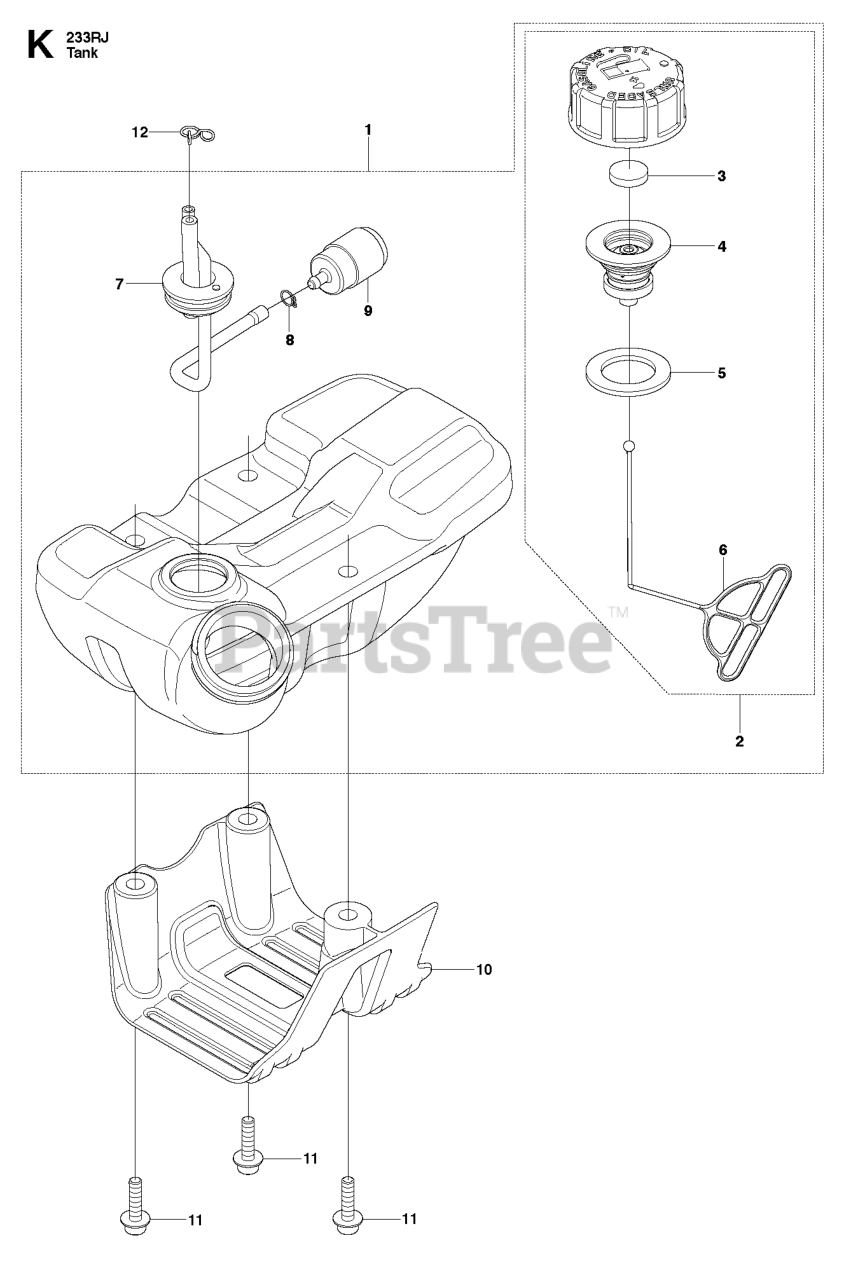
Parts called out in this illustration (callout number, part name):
2	CAP ASSY
3	FILTER
4	HOLDER ASSY
5	PACKING
6	STOPPER
7	PIPE-C
8	CLIP
9	FILTER
11	BOLT
12	CLIP
